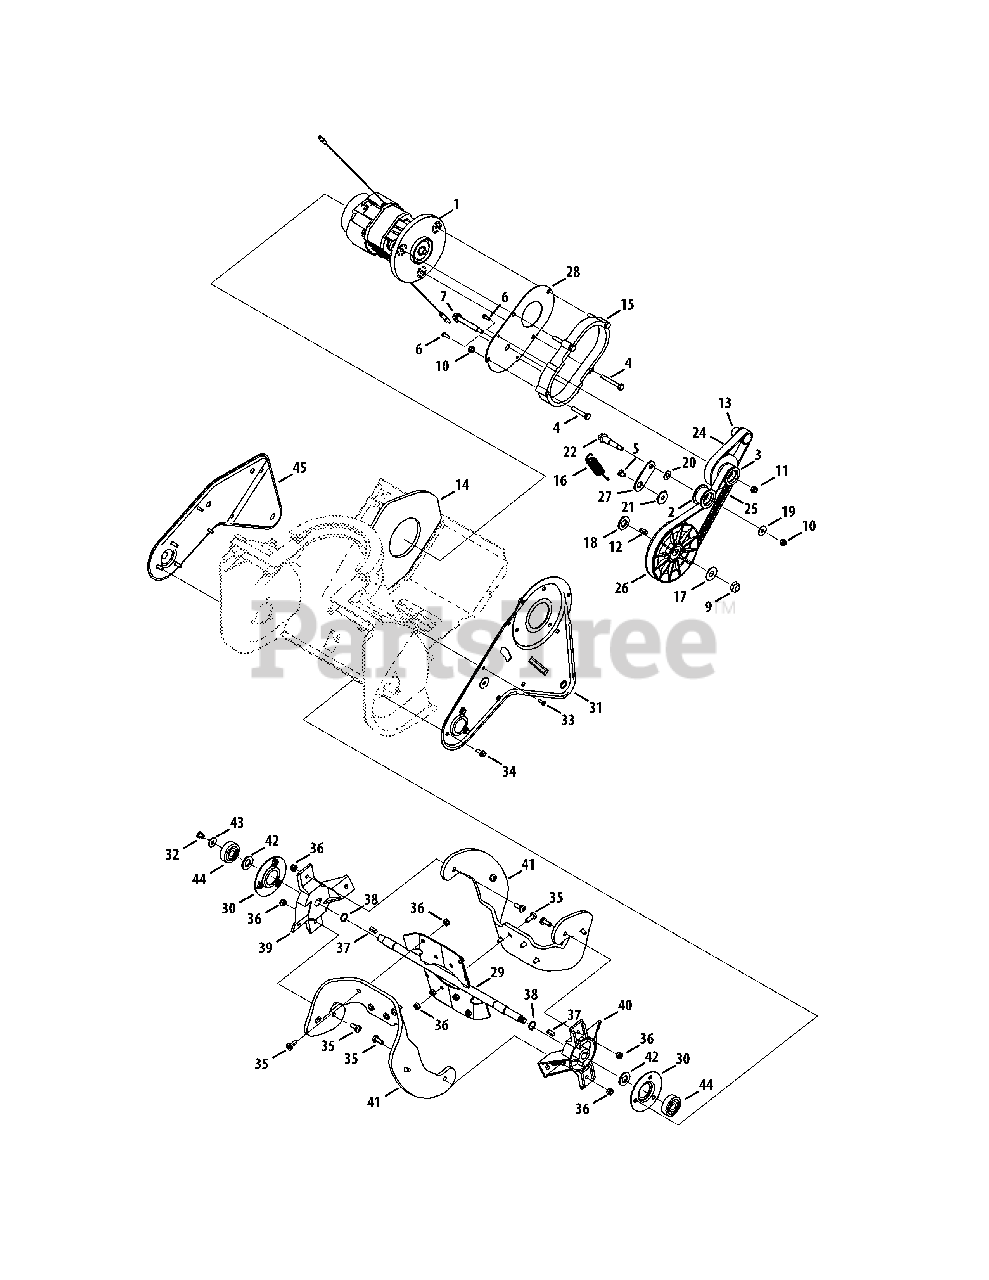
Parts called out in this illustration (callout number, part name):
1	Motor Assembly
2	Pulley Assembly, Idler
3	Pulley Assembly
4	Screw, M6-1, 35.00
5	Screw, Hex Screw, M6 x 8mm
6	Screw, Tap, M4.2 x 1.4 x 13
7	Screw, Hex Flange, M8-1.25, 60mm
8	Screw, M6-1, 45.00
9	Nut, Hex, Torque, M10
10	Nut, Hex Lock, M6-1
11	Nut, Hex Lock, M8-1.25, Nylon
12	Key, Square, 5 x 5 x 13
13	Pulley, 5mm, 15 Tooth
14	Gasket, Foam
15	Spacer, Motor Mount
16	Extension Spring, Idler
17	Washer, Flat, .406 x 1.0 x .030
18	Washer, Flat, M12
19	Washer, Flat, 6.4 Id x 18 OD
20	Washer, Flat, 8.4 x 16 x 1.60
21	Spacer, Shoulder, Hex, M6
22	Screw, Shoulder
23	Spacer, 8.35 x 16 x 11.65
25	Belt, Poly, 6 Rib
26	Pulley, Auger, 6 Rib
27	Bracket, Idler
28	Plate, Motor Mount
29	Auger Weldment
30	Plate, Bearing Retainer
31	Plate, LH Side
32	Screw, Hex Screw, M6 x 8mm
33	Screw, Tap, M4.2 x 1.4 x 13
34	Screw, Hex Flange, M5 x 13mm
35	Screw, M6 -1, 16
36	Nut, Hex Lock, M6-1, Nylon
37	Key, Square, 5x5x13
38	Snap Ring, External
39	Bracket, Shovel, Mount, RH
40	Bracket, Paddle, Mount, LH
41	Paddle Auger, Rubber
42	Washer, Flat, M12, Ansi Narrow
43	Washer, Flat, 6.4 Idx18 OD
44	Bearing, Ball, 12 x 37 x 12
45	Plate Right, Outer
